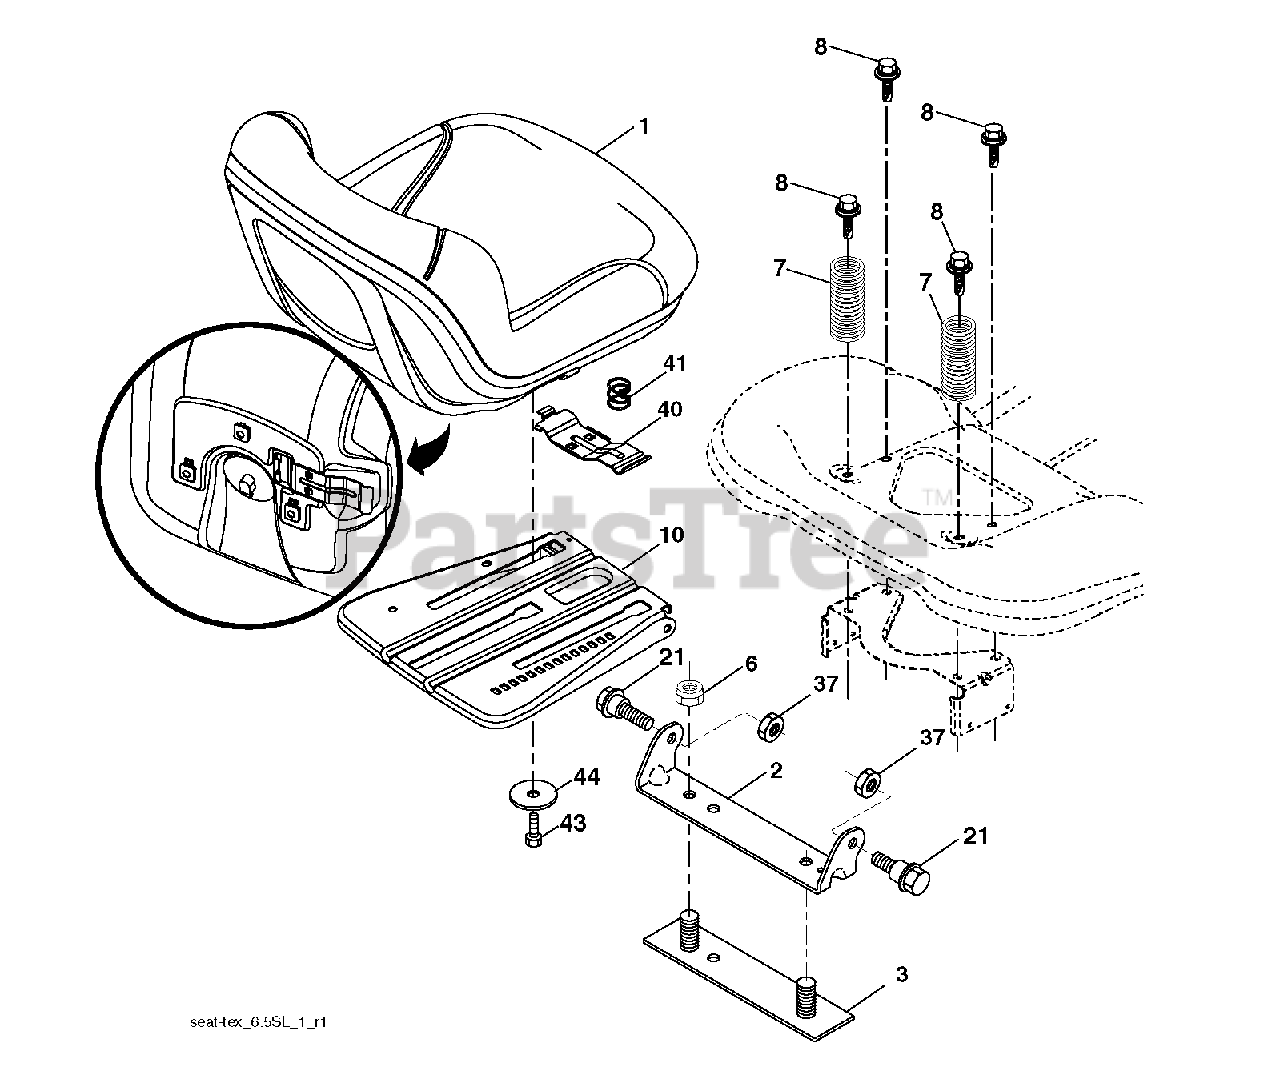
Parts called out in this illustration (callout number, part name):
2	BRKT.PIVOT.FENDER
3	STRAP
7	SPRING COMPRESSION
8	BOLT, 5/16-18 X 1 3/4
10	PAN.ASM.SEAT.3PT
21	BOLT, SHOULDER
40	HANDLE.SLIDE.SEAT.TEX.
41	SPRING.LATCH.SEAT.TEX
44	WASHER 13/32 X 2-3/8 X 12GA
